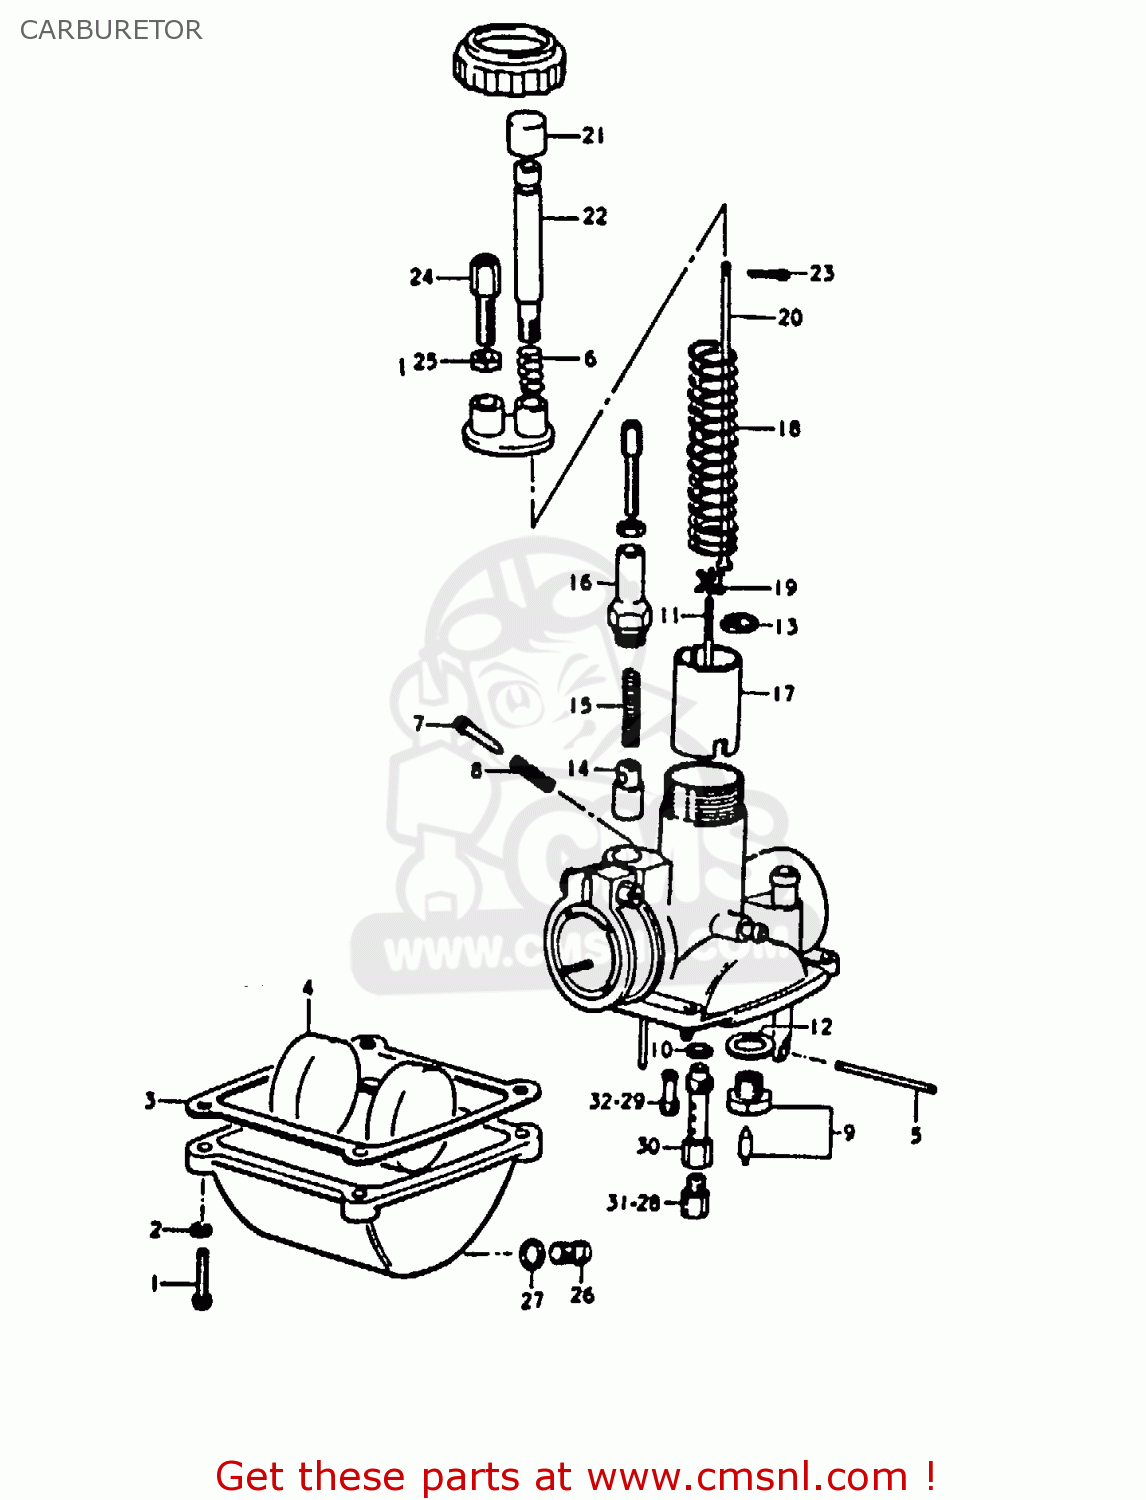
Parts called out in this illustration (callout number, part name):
1	SCREW
2	LOCK WASHER
3	GASKET,FLOAT CHAMBER (NAS)
4	FLOAT
5	PIN,FLOAT
6	SPRING,THROTTLE STOP SCREW
7	SCREW,PILOT AIR
8	SPRING
9	VALVE ASSY,NEEDLE
10	WASHER
11	NEEDLE,JET
12	GASKET,NEEDLE VALVE (NAS)
13	CLIP,NEEDLE
14	PLUNGER,STARTER
15	SPRING
16	CAP,STARTER PLUNGER
17	VALVE,THROTTLE
18	SPRING,THROTTLE VALVE
19	STOPPER,NEEDLE CLIP
20	ROD,THROTTLE VALVE ADJUST
21	CAP,THROTTLE VALVE STOP SCREW
22	SCREW,THROTTLE STOP
23	PIN 12X10
24	ADJUSTER,CABLE
25	NUT
26	PLUG
27	GASKET,DRAIN,PLUG (NAS)
28	JET,MAIN
29	JET,PILOT
30	JET,NEEDLE
31	JET,MAIN
32	JET,PILOT
